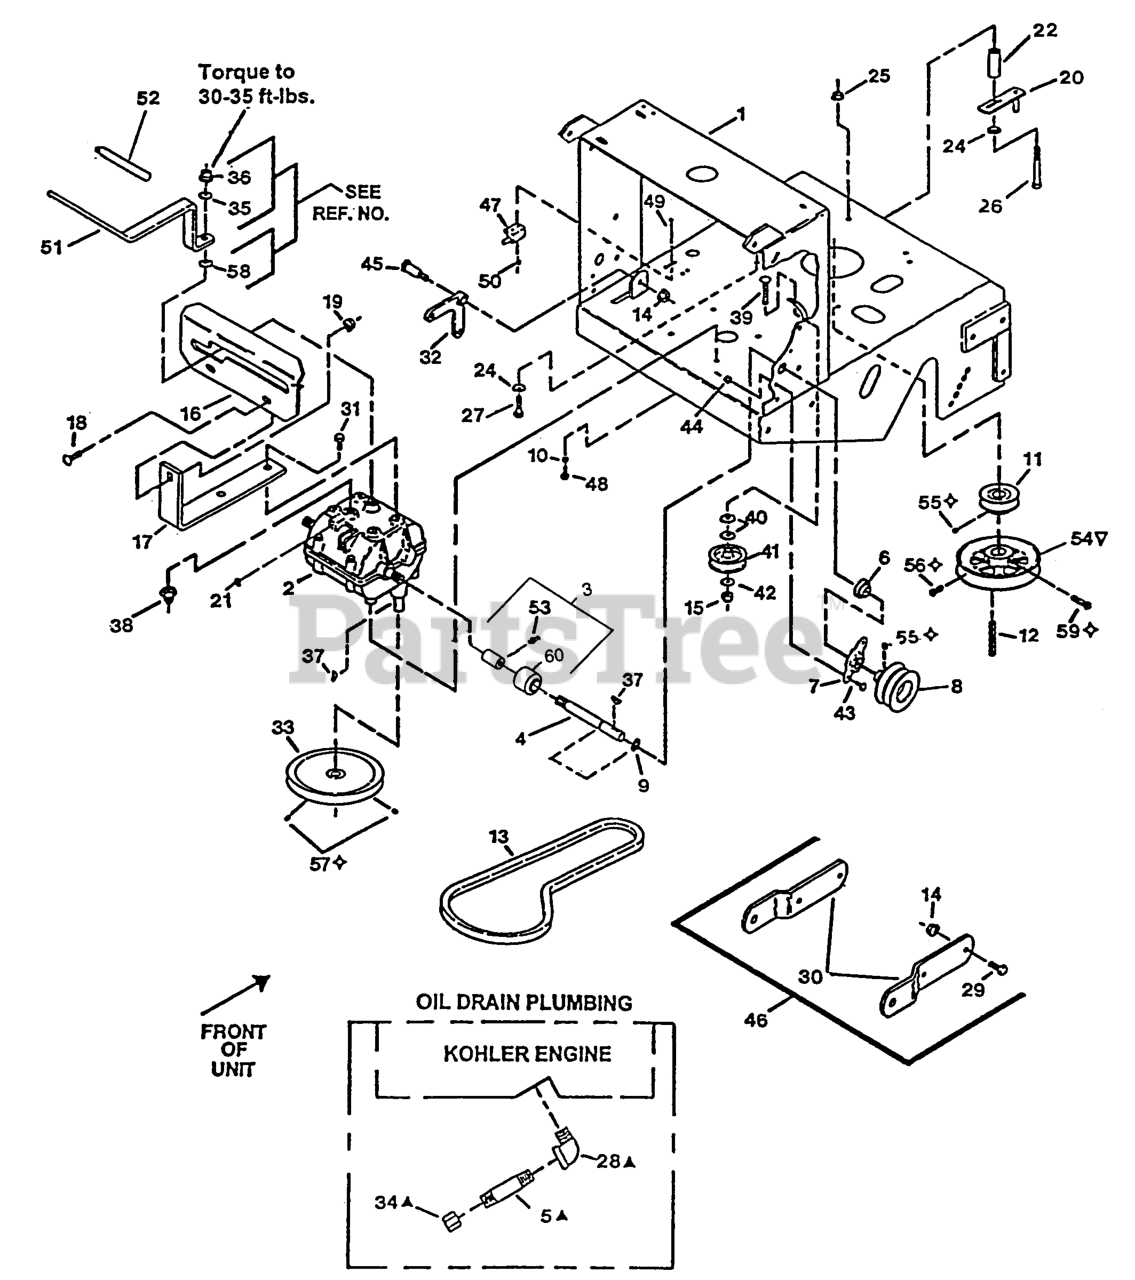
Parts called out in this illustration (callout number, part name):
3	ASM,COUPLER/ZERK
4	SHAFT-TRANSMISSION
5	NIPPLE
6	BEARING-SHAFT
7	FLANGE-OUTPUT
10	WASHER-LOCK
11	SHEAVE-TRANSMISSION
12	KEY,MACH 1/4X1/4X2-5/8
13	BELT,TRANS DRIVE
17	BRACKET-PLATE, SHIFT
20	GUIDE-BELT
21	BALL,DETENT (SERVICE ONL
23	KIT,TRANSMISSION UPDATE
24	WASHER-SPRING
28	FITTING-ELBOW-90
30	HITCH-SULKY
32	BELLCRANK
33	SHEAVE-TRANSMISSION
34	CAP-HEX
38	SWITCH-START, NEUTRAL
45	BOLT-SHOULDER
46	Sulky Hitch Kit, Metro
47	SWITCH-OPEN, NORMALLY
54	SHEAVE,BLADE DRIVE
55	SCREW-SET
56	SCREW-SET
